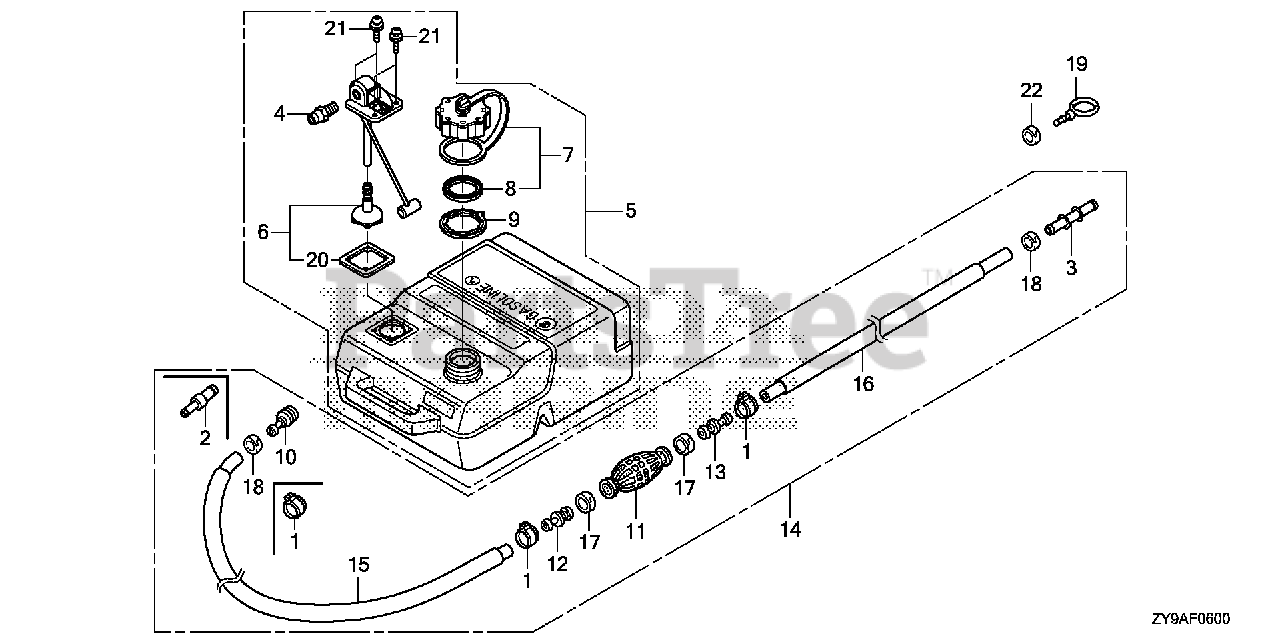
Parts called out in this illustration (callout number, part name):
1	CLAMP, FUEL TUBE (14.0)
2	JOINT, FUEL TUBE
3	JOINT, FUEL TUBE
4	FITTING, QUICK DISCONNECT
5	TANK ASSY., FUEL
6	FILTER KIT, FUEL
7	CAP, FUEL FILLER
8	GASKET, FUEL CAP
9	RETAINER, PRESSURE RELIEF
10	CONNECTOR, FUEL
11	BULB, PRIMER
12	VALVE, IN.
13	VALVE, OUTLET
14	TUBE ASSY., FUEL TANK
14	TUBE ASSY., FUEL TANK (CONNECTOR TYPE)
15	TUBE, FUEL LONG (7.3X2000)
15	TUBE, FUEL SHORT
16	TUBE, FUEL LONG (7.3X2000)
16	TUBE, FUEL SHORT
17	BAND, TUBE CLIP (20MM)
18	BAND, TUBE CLIP (12.5MM)
19	PLUG, FUEL TUBE
20	GASKET, FUEL PICK-UP
21	BOLT-WASHER (5MM) (SEAL)
22	BAND, TUBE CLIP (12.5MM)
